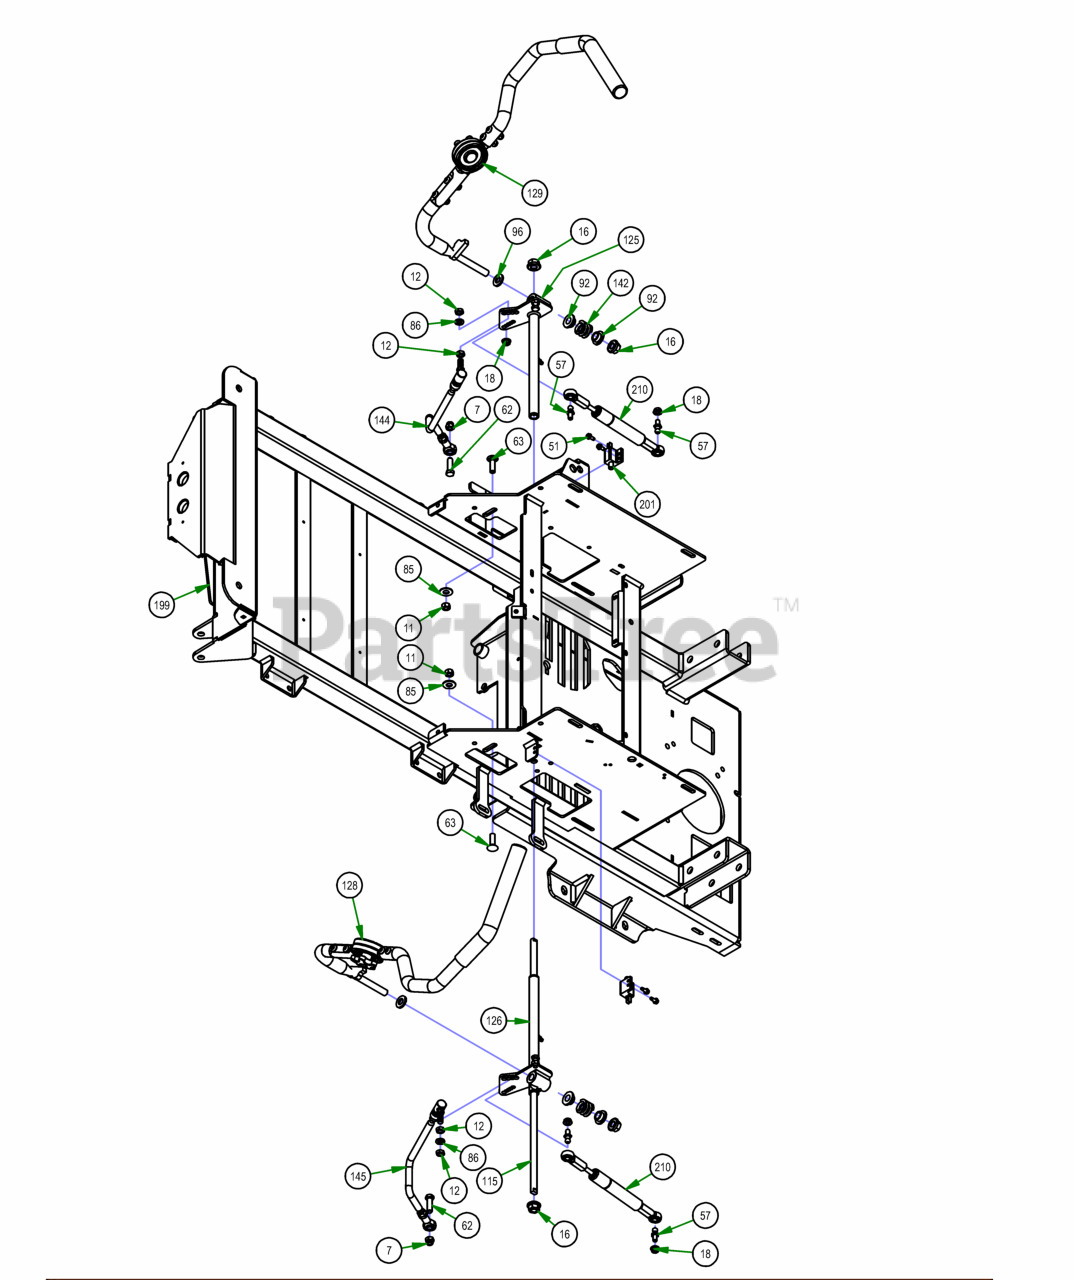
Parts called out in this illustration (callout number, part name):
7	3/8-16 NYLON INSERT LOCKNUT ZINC
11	3/8-16 HEX NUT ZINC
12	3/8-24 HEX NUT ZINC YELLOW
16	1/2-13 NYLON INSERT FLANGE LOCKNUT ZINC
18	5/16-18 HEX SERRATED FLANGE NUT HARD/ZINC
51	12-24 X 1/2 HEX WASHER UNLSOT F TCS ZINC
57	10mm Damper Ball Stud-Steering
62	3/8-16 X 1-1/4 HEX CAP SCREW (GR.5) ZINC
63	3/8-16 X 1-1/4 CARRIAGE BOLT ZINC
85	3/8 FLAT WASHER USS (1" OD) ZINC
86	3/8 SPLIT LOCKWASHER ZINC
92	.525 ID SHOULDER WASHER NYLON
96	.505 ID X 1.000 OD X .125 THICK FLAT WASHER NYLON
115	2021 Maverick Steering Actuator Rod
125	2021 Maverick Drive Arm Actuator RH Assembly
126	2021 Maverick Drive Arm Actuator LH Assembly
128	2018 Adjustable Steering Arm - Left
129	2018 Adjustable Steering Arm - Right
142	Drive Lever Spring
144	Push Rod-Right
145	Push Rod-Left
199	2021 Maverick Frame - Painted
201	Safety Switch
210	Steering Damper
